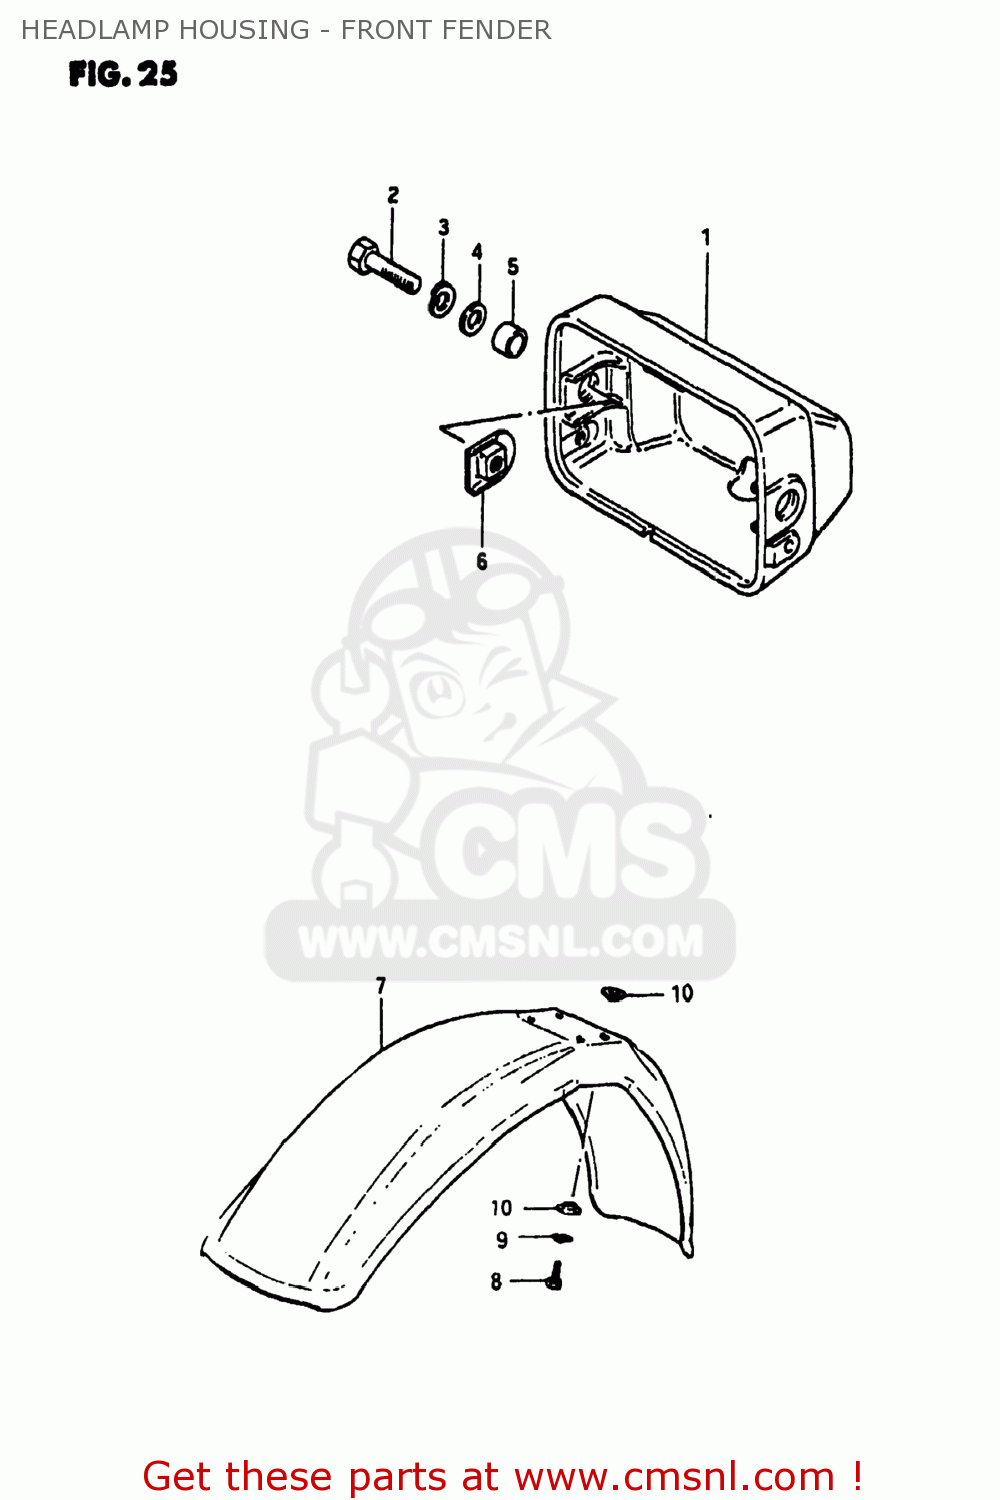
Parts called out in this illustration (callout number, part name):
1	HOUSING,HEADLAMP
2	BOLT
3	LOCK WASHER
4	WASHER
5	SPACER (8.8X12X7)
6	PLATE,HEADLAMP HOUSING
7	FENDER,FRONT
8	BOLT, UPPER
9	LOCK WASHER
10	WASHER
